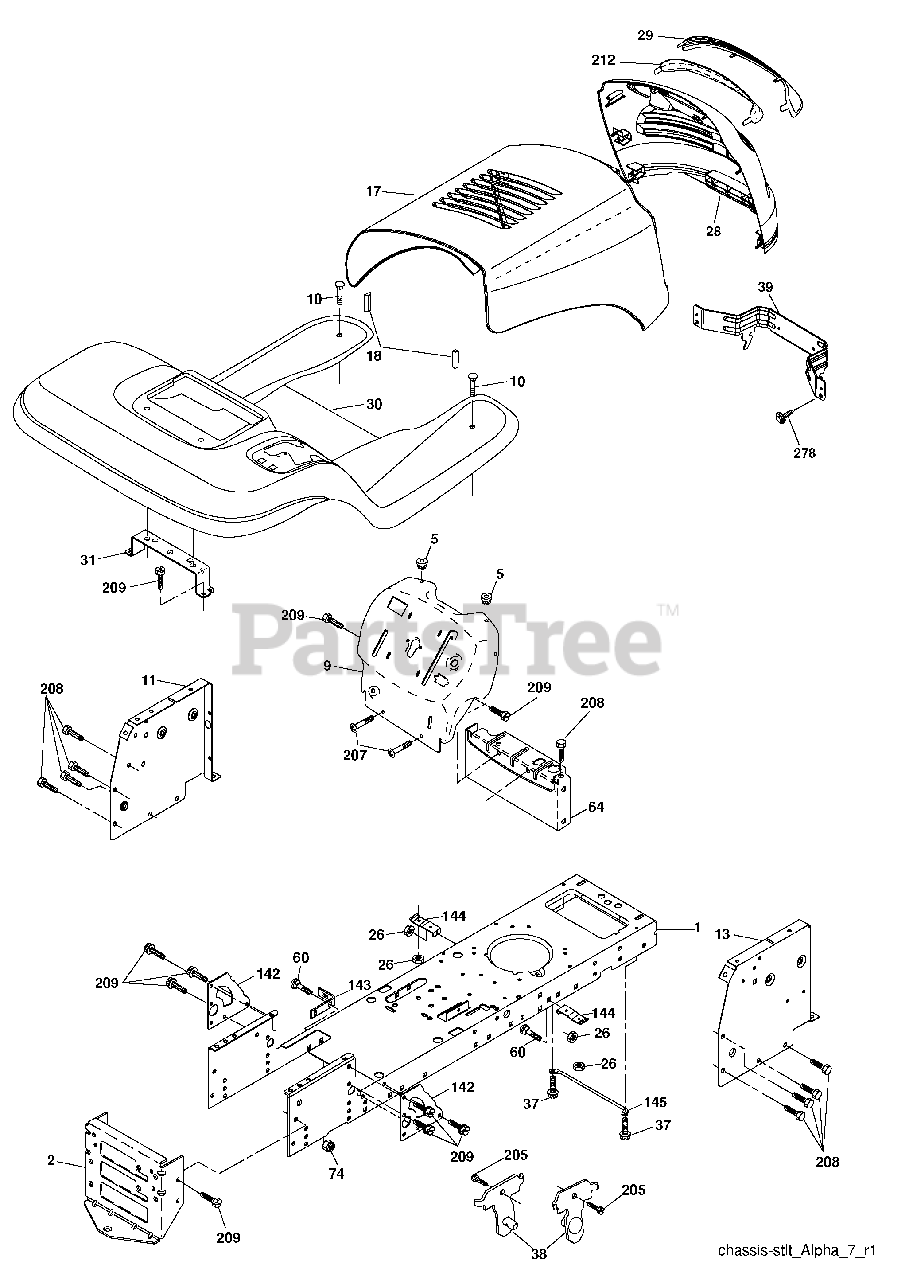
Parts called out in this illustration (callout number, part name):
1	Chassis
2	Drawbar, Stretch
5	Bumper, Hood/Dash
9	Dash
10	Bolt, Carriage 3/8-16 x 1
11	Panel Dash LH
13	Panel Slkscr Dash RH
17	Hood
18	Bumper Hood
26	Nut Lock Hex w/Ins 3/8-16 unc
28	Grille
29	Lens Grille Basic Bar
31	Bracket Fender Repl 109873X
37	Screw Thdrol 5/16-18 x 1/2 TYT
38	Bracket Asm. Pivot Mower
39	Bracket Pivot
60	Bolt Carr 3/8-16 x 3/4
64	Dash Lower
74	Nut 3/8-16 Center Lock
142	Plate Reinforcement
143	Bracket Swaybar Chassis
144	Bracket Footrest
145	Rod Pivot Hood
205	Screw Thdrol 3/8-16 x 1/2
207	Screw Thdrol 5/16-18 x 1/2
208	Screw Thdrol 3/8-16 x 1/2
209	Screw Hex Wsh Thdrol 3/8-16
212	Insert Lens Reflect
278	Screw #10 x 0.750
278	Plug Button Blk 359 Dia Choke
278	Plug Dome Plastic
